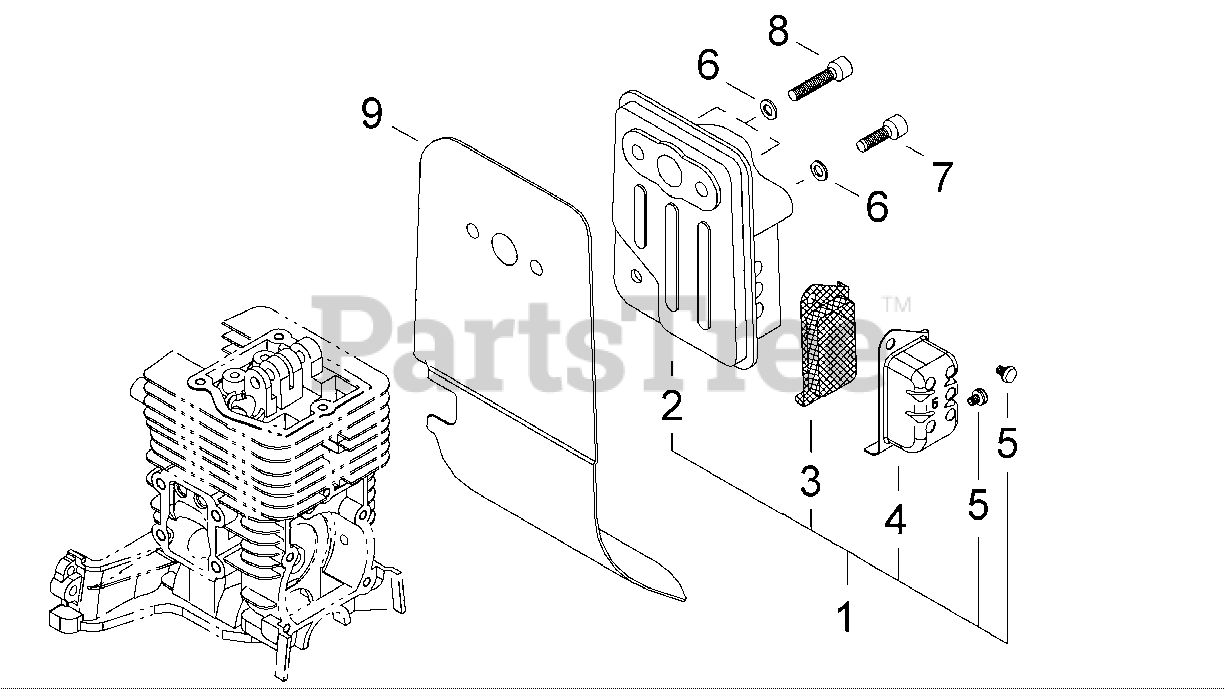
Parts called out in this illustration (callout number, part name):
1	MUFFLER ASSY
2	MUFFLER
3	SCREEN, SPARK ARRESTOR
4	GUIDE, EXHAUST
5	SCREW - 4X6
6	WASHER - 5
7	SCREW - 5X16
8	SCREW - 5X25
9	SHIELD, EXHAUST
